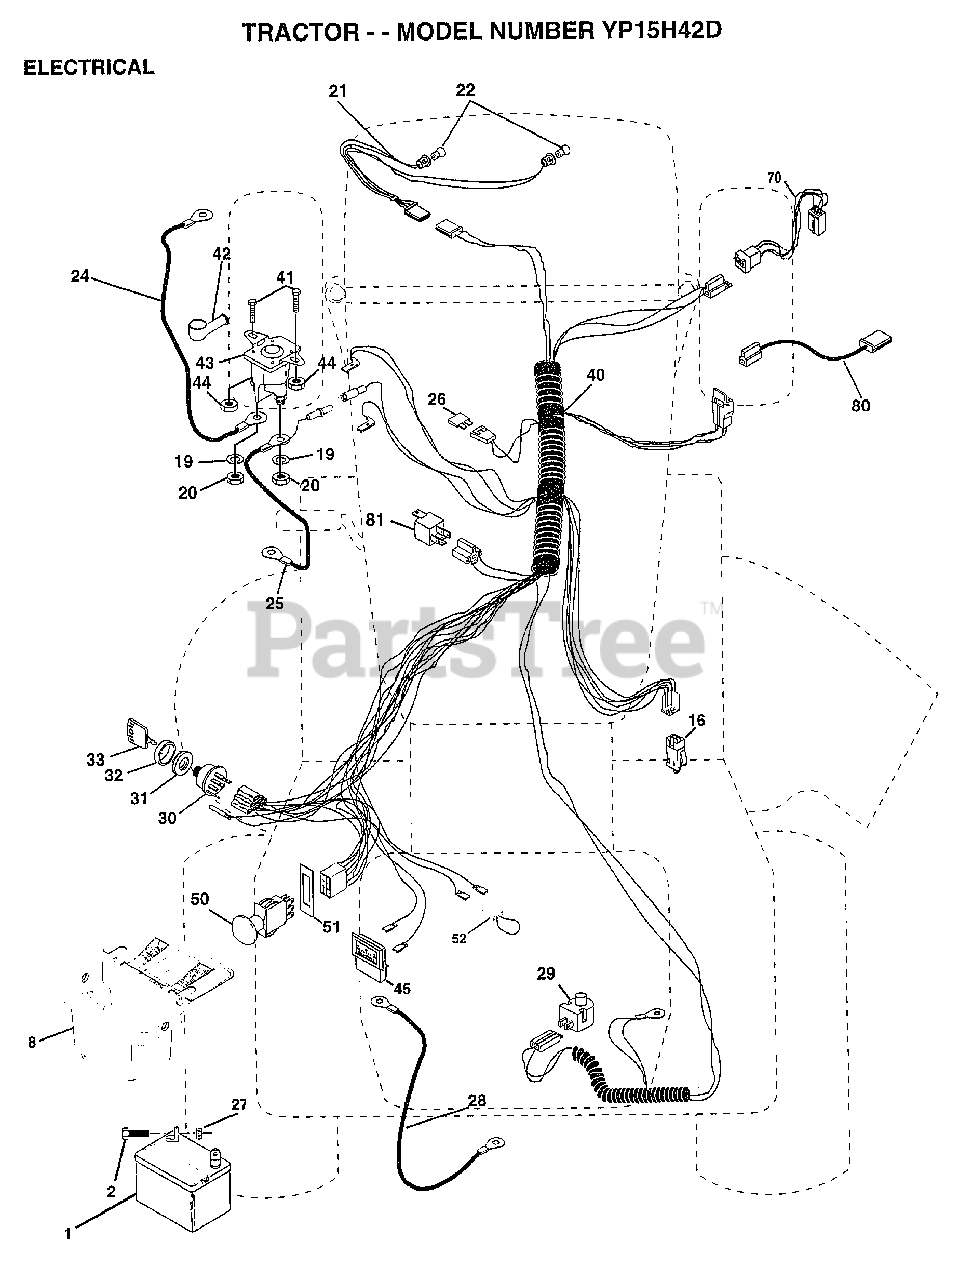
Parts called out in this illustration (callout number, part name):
2	BOLT LT
8	"CASE,BATTERY.MECH"
16	SWITCH INTERLOCK
20	NUT
21	HARNESS.ASM.LIGHT W/4152J
22	HEADLAMP BULB
24	"CABLE T, BATTERY"
25	CABLE.BTRY.6GA.RD
26	FUSE.15 AMP
28	CABLE T
29	SWITCH.PLUNGER
30	SWITCH IGN 4POS
31	NUT IGNITION
32	COVER KEY SWITCH
33	KEY
40	HARNESS.IGNITION
41	BOLT HXHD FIN
44	NUT HXKEP 1/4X20
45	AMMETER
50	PTO SWITCH.BLK
51	RING RETAIN PTO
52	PROTECTION LOOP
70	HARNESS.ENGINE.KOHL
80	HARNESS.CLUT.EVX.
81	RELAY ASSY T
